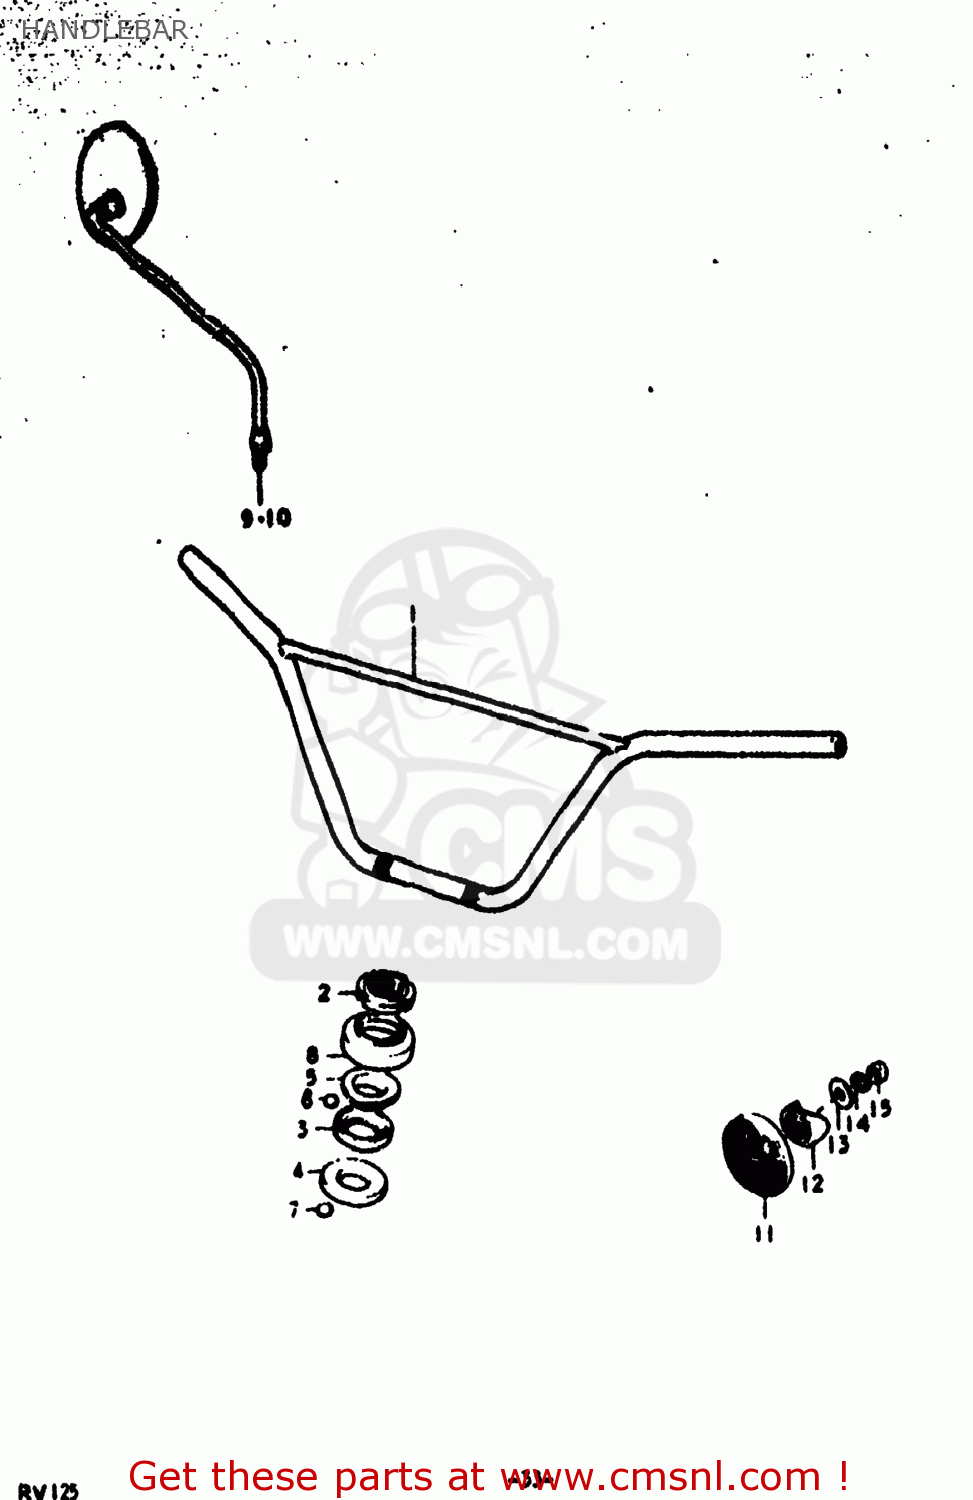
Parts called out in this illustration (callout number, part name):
1	HANDLEBAR
2	NUT,STEERING STEM(25X44X10)
3	RACE,STEERING INNER UPR
4	LACE,STEERING INNER LWR
5	RACE,STEERING OUTER UPR
6	BALL
7	BALL
8	DUST SEAL,STEERING UPR
9	MIRROR ASSEMBLY,RIGHT
10	MIRROR ASSEMBLY,LEFT
11	REFLEX REFLECTOR ASSEMBLY
12	SPACER
13	WASHER
14	LOCK WASHER
15	NUT
